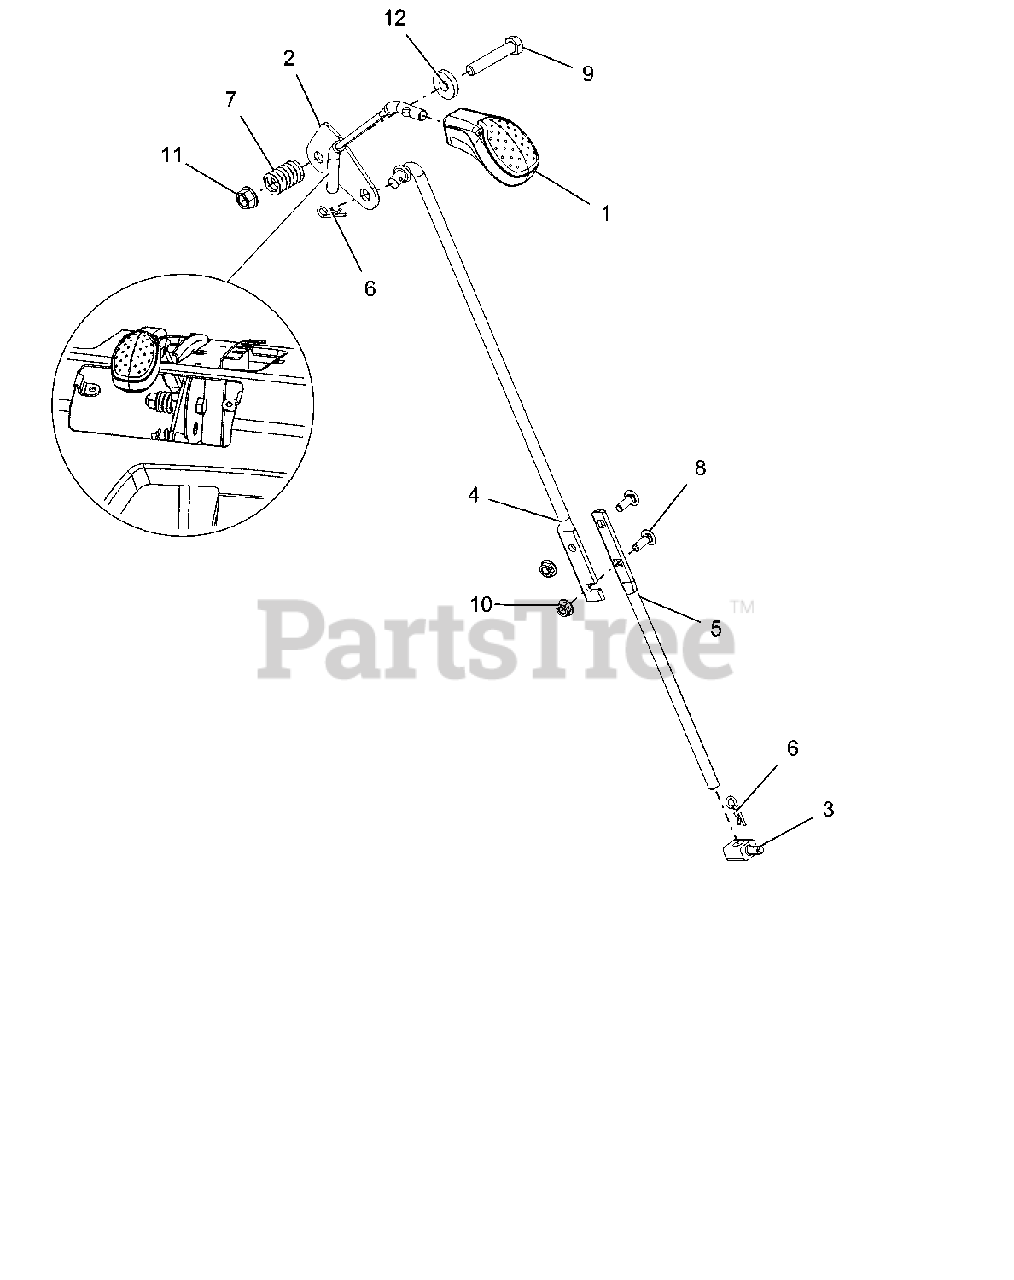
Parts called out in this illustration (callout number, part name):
1	KNOB, CONTROL, DASH
2	WELDMENT,LG DASH SPEED CONTROL
3	PIVOT,SHIFT ROD .375-16(TRUNN)
4	ROD, SHIFT - UPPER
5	ROD, SHIFT - LOWER
6	PIN-HAIR INT .08X.18X1.18 YWZC
7	SG-COMP .125X.781X1.250
8	BLT-RDHDSQNK .25-20X.75 G5YZ
9	BLT-HEX .38-16X2.00 GR5 YWZC
10	NUT-LK-CTR-FLG .25-20 YWZC
11	NUT-LK-TOP-FLG .38-16 YWZC
12	WSHR-FL-STL .406X1.00X.188 YWZ
